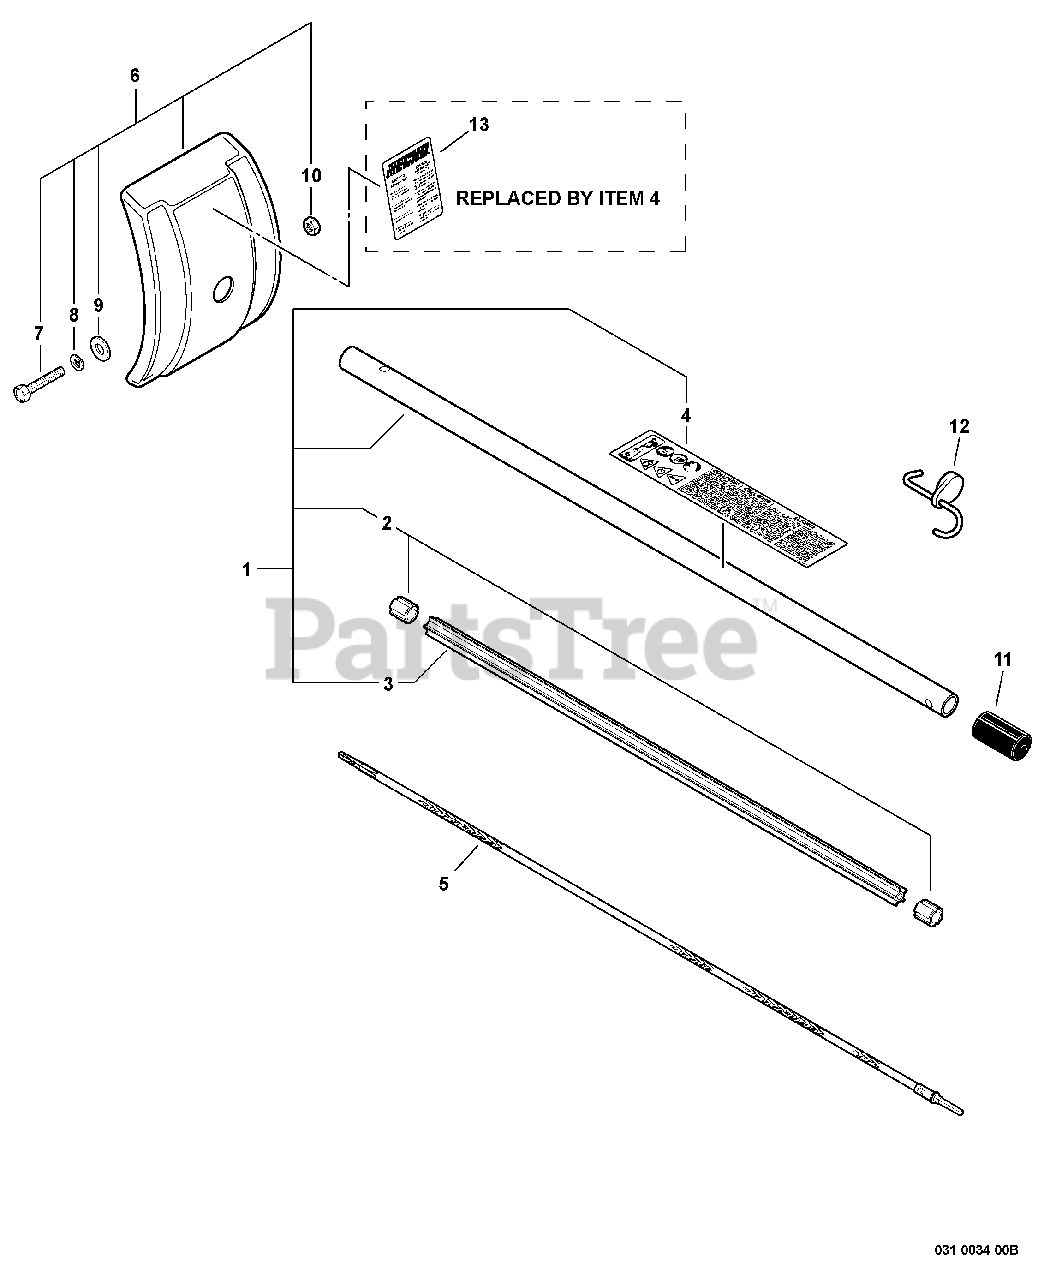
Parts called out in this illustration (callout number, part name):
1	MAIN PIPE ASSY
3	LINER - FLEXIBLE
4	LABEL - CAUTION
5	DRIVESHAFT - FLEXIBLE
6	DEBRIS SHIELD KIT
7	BOLT - 6X20
8	LOCKWASHER - 6
9	WASHER - 6
10	LOCKNUT - 6
12	PAS ATTACHMENT HANGER
13	LABEL - CAUTION
